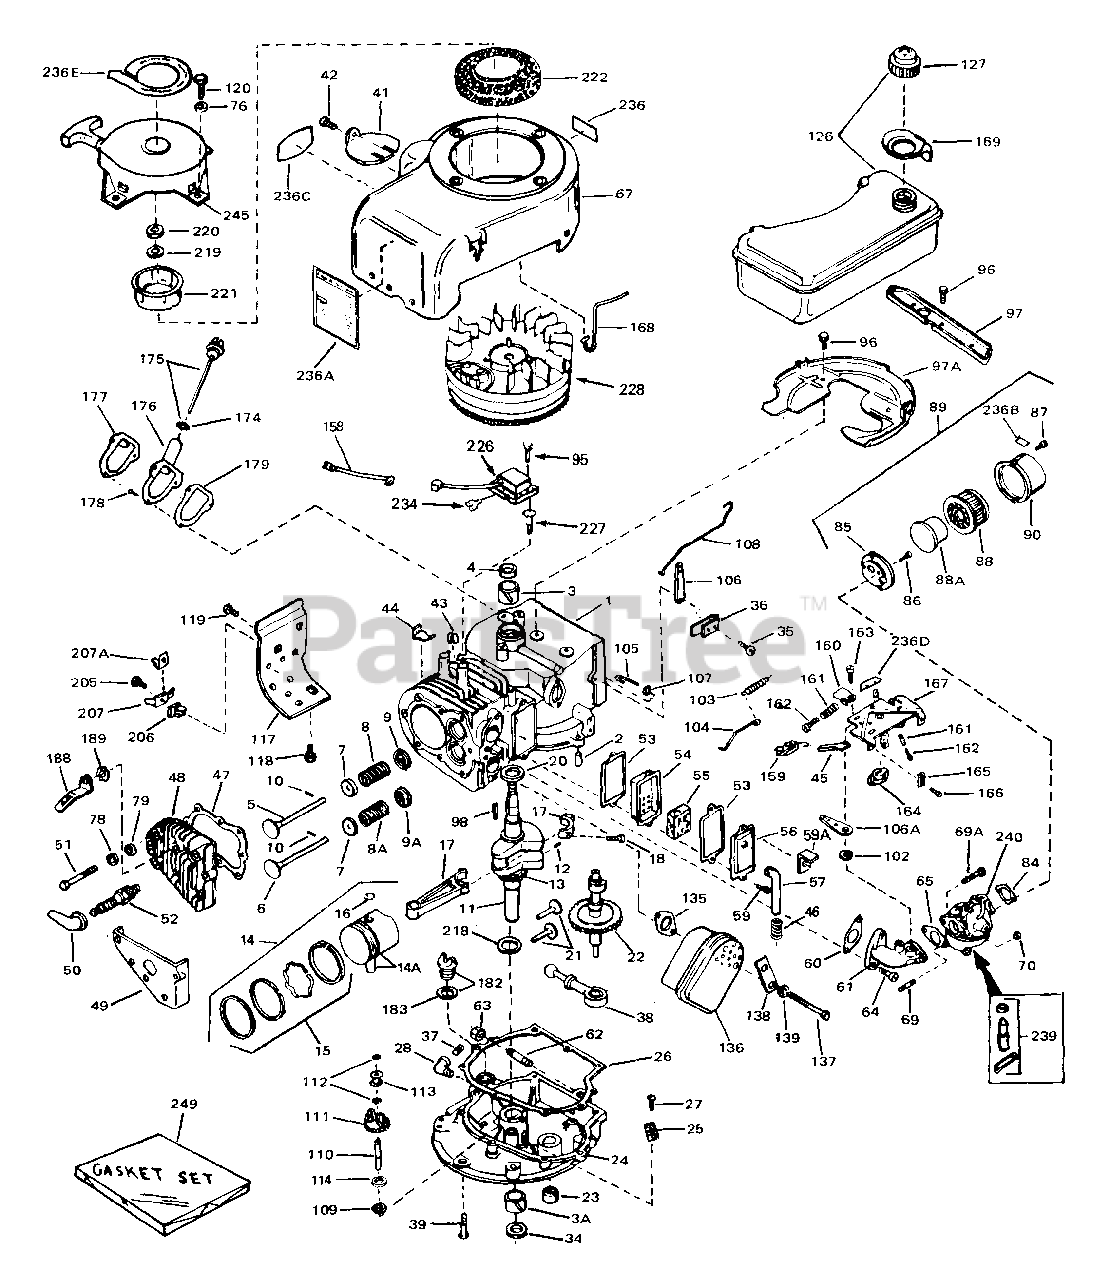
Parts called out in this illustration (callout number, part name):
1	"Cylinder Assy. (2-3/4" Bore)
2	Pin, Dowel
3	Bushing, Crankshaft
3A	Bushing, Crankshaft
4	Seal, Oil
5	Valve, Intake (Standard)
5	Valve, Intake (1/32" oversize)
6	Valve, Exhaust (Standard)
6	Valve, Exhaust (1/32" oversize)
7	Cap, Upper valve spring
8	Spring, Valve
8A	Spring, Valve
9	Cap, Lower valve spring
9A	Cap, Lower valve spring
10	Pin, Valve spring retaining
11	Crankshaft Assy.
12	Pin, Crankshaft gear
13	Gear, Crankshaft
14	Piston, Pin & Ring Assy. (Std.)
14	Piston, Pin & Ring Assy. (.010 oversi ze)
14	Piston, Pin & Ring Assy. (.020 oversi ze)
14A	Piston & Pin Assy. (Std.) (2-3/4")
14A	Piston & Pin Assy. (.010 oversize)
14A	Piston & Pin Assy. (.020 oversize)
15	Ring Set, Piston (Std.) (2-3/4")
15	Ring Set, Piston (.010 oversize)
15	Ring Set, Piston (.020 oversize)
16	Ring, Piston pin retaining
17	Rod Assy., Connecting
18	Screw, Connecting rod (Two pieces)
20	Washer, Thrust
21	Lifter, Valve
22	Camshaft (Mech. Compression Release)
24	Flange, Mounting
25	Screen, Oil strainer
26	Gasket, Mounting flange
27	Screw, Hex hd. shakeproof, 8-32 x 5/1 6
34	Seal, Oil
35	Screw, Hex washer hd., 8-32 x 5/16
36	Clamp, Governor
37	Plug, Drain (1/4-18 sq. hd.)
37	Plug, Drain (1/4-18 Hex countersunk
38	Pump Assy., Oil
39	Screw, Hex hd. Sems, 1/4-20 x 1-1/4
43	Clip, Wire retaining
44	Clip, Fuel line
47	Gasket, Cylinder head
48	Head, Cylinder
49	Cover, Cylinder head
50	Cover, Spark plug
51	Screw, Hex flange hd., 5/16-18 x 2-1/ 2
52	Plug, Spark (Champion J-8C or equival ent)
52	Resistor Spark Plug
53	Gasket, Breather
54	Body, Breather
55	Element, Breather
56	Cover, Valve chamber
57	Tube, Breather
59	Screw, Fil. hd., 10-24 x 1/2
60	Gasket, Intake pipe
61	Pipe, Intake
64	Screw, Fil. hd. Sems, 5/16-18 x 1-1/8
65	Gasket, Carburetor
67	Housing Assy., Blower (5.56 dia. star ter
69	Stud, Intake pipe
69A	Screw, Hex hd. Sems, 1/4-20 x 13/16
70	Nut & Lockwasher, 1/4-28
76	Washer, Flat
76	Washer, Flat (1/4 Plain)
78	Washer, Belleville
79	Washer, Flat
84	Gasket, Air cleaner
85	Bracket, Air cleaner
86	Screw, Fil. hd. Sems, 10-32 x 1/2
87	Screw, Fil. hd. Sems, 8-32 x 3/8
88	Element, Air cleaner (Paper)
89	Cleaner Assy., Air (Poly)
89	Cleaner Assy., Air (Paper)
90	Body, Air cleaner
95	Screw, Hex hd. Sems, 1/4-20 x 5/8 (St d.
95	Screw, Hex hd. Sems, 1/4-20 x 1-1/8 ( Std.
96	Screw, Hex washer hd. Durlok, 1/4-20 x 5/8
97A	Baffle, Blower housing (Without elect ric
97A	Baffle, Blower housing (With electric
98	Key, Flywheel
103	Spring, Governor
104	Link, Governor spring
105	Rod, Governor
106	Lever, Governor
107	Washer, Flat
108	Link, Throttle
109	Governor, Spacer Assy.
110	Shaft, Mechanical governor
111	Gear Assy., Governor
112	Ring, Retaining
113	Spool, Governor
114	Washer, Flat
117	Extension, Blower housing
118	Screw, Fil. hd. Sems, 10-24 x 1/2
119	Screw, Hex hd. Sems, 1/4-20 x 1/2
120	Screw, Pan hd. Sems, 1/4-28 x 7/16
126	Tank Assy., Fuel (Charcoal Gray Poly) (2
127	Cap, Fuel filler (Red Plastic) (Spurt
127	Cap, Fuel filler (White Plastic) (Std .)
135	Gasket, Exhaust
136	Muffler
137	Screw, Hex hd., 5/16-18 x 2-3/4
138	Plate, Muffler locking
139	Lockwasher
158	Wire, Ground (Female fittings both en ds)
159	Terminal Assy.
160	Bracket, Control
161	Spring, Compression
162	Screw, Hex hd., 10-32 x 1 (Drilled th ru)
163	Screw, Hex washer hd. self-tap, Sems, 10-24
164	Knob, Speed control
165	Clip, Conduit
166	Screw, Hex hd. Sems, 10-32 x 3/8
167	Control Assy., Speed
168	Clamp, Tank holddown
169	Deflector, Fuel
174	Gasket, Dipstick
175	Dipstick, Oil (Screw In) (2.34" long)
219	Washer, Belleville
221	Cup, Starter
222	Screen, Starter cup
236	Decal, Instruction
236B	Decal, Air cleaner
239	Inlet Needle, Seat & Clip Assy.
240	Carburetor
245	Starter, Rewind
249	Gasket Set
